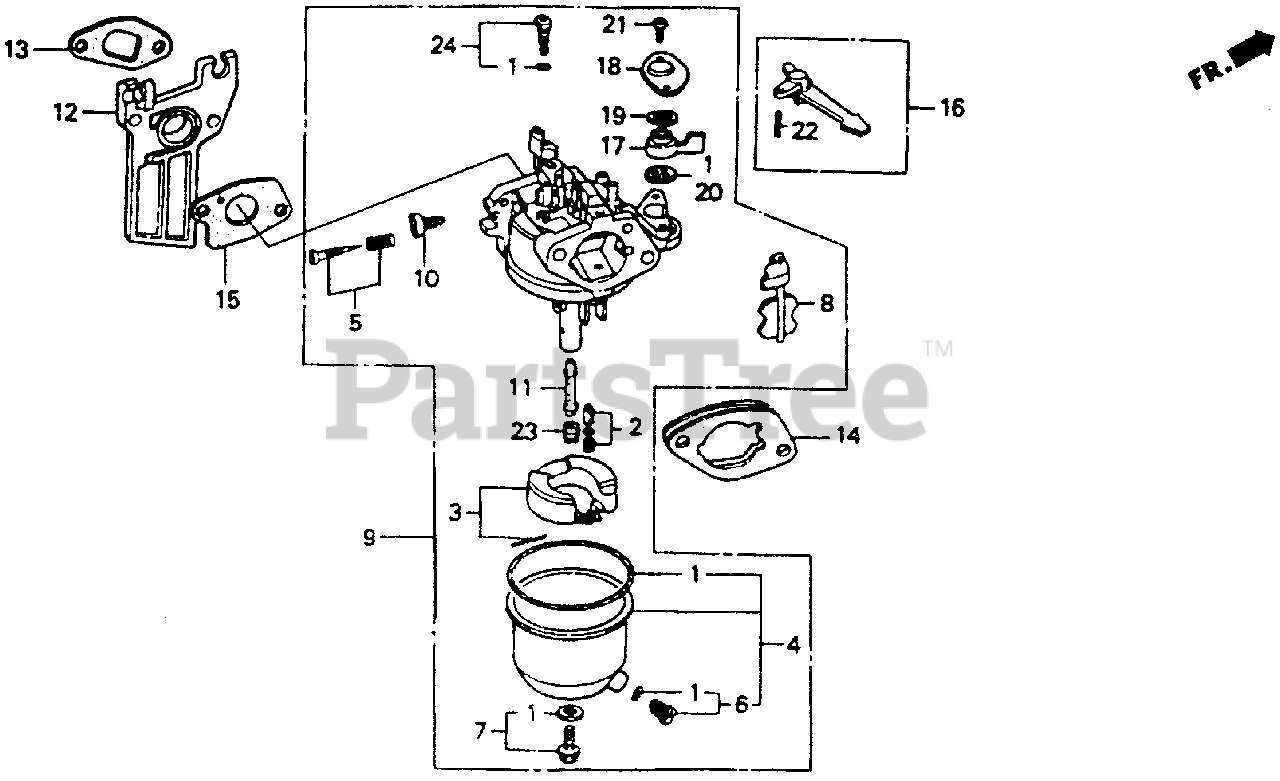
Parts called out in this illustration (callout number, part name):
1	GASKET SET
2	VALVE SET, FLOAT
4	CHAMBER SET, FLOAT
5	SCREW SET, PILOT
6	SCREW SET, DRAIN
7	SCREW SET
9	CARBURETOR ASSY. (BE05A B)
9	CARBURETOR ASSY. (BE05A D)
9	CARBURETOR ASSY. (BE05A E)
10	SCREW, THROTTLE STOP
11	NOZZLE, MAIN
12	INSULATOR, CARBURETOR
13	GASKET, INSULATOR
14	SPACER, CARBURETOR
15	GASKET, CARBURETOR
16	LEVER, CHOKE (STD)
17	LEVER, VALVE
18	PLATE, LEVER SETTING
19	SPRING, PETCOCK LEVER
20	GASKET, PETCOCK
21	SCREW, PAN (3X8)
22	PIN, SPRING (2X12)
23	JET, MAIN (#62)
23	JET, MAIN (#65)
23	JET, MAIN (#68)
24	JET SET, PILOT (#35)
